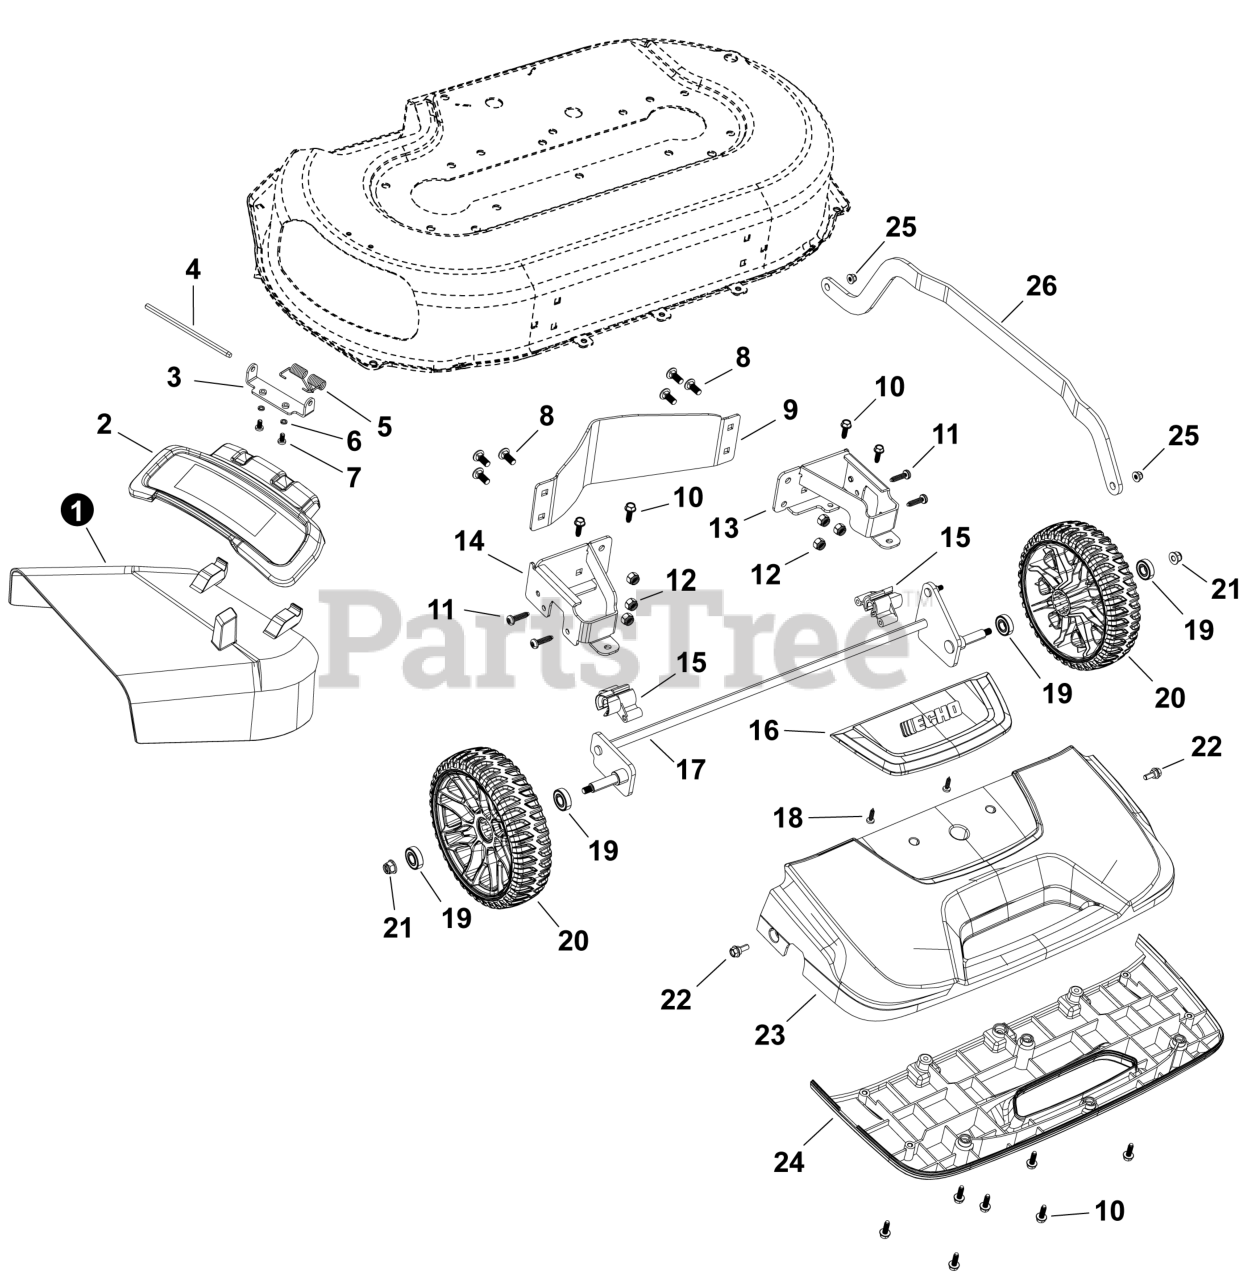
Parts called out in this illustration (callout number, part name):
1	DEFLECTOR, EXHAUST
2	COVER, SIDE DISCHARGE
3	MOUNTING PLATE, SIDE COVER
4	ROD, SIDE DISCHARGE COVER
5	SPRING, SIDE DISCHARGE COVER
9	DEFLECTOR, FRONT AIR
13	BRACKET, FRONT LEFT WHEEL
14	BRACKET, FRONT RIGHT WHEEL
15	BUSHING, FRONT GUIDE
16	COVER, LOGO
17	AXLE, FRONT
20	WHEEL, FRONT
23	COVER, FRONT
24	BASE, FRONT COVER
26	ROD, HEIGHT ADJUSTMENT
